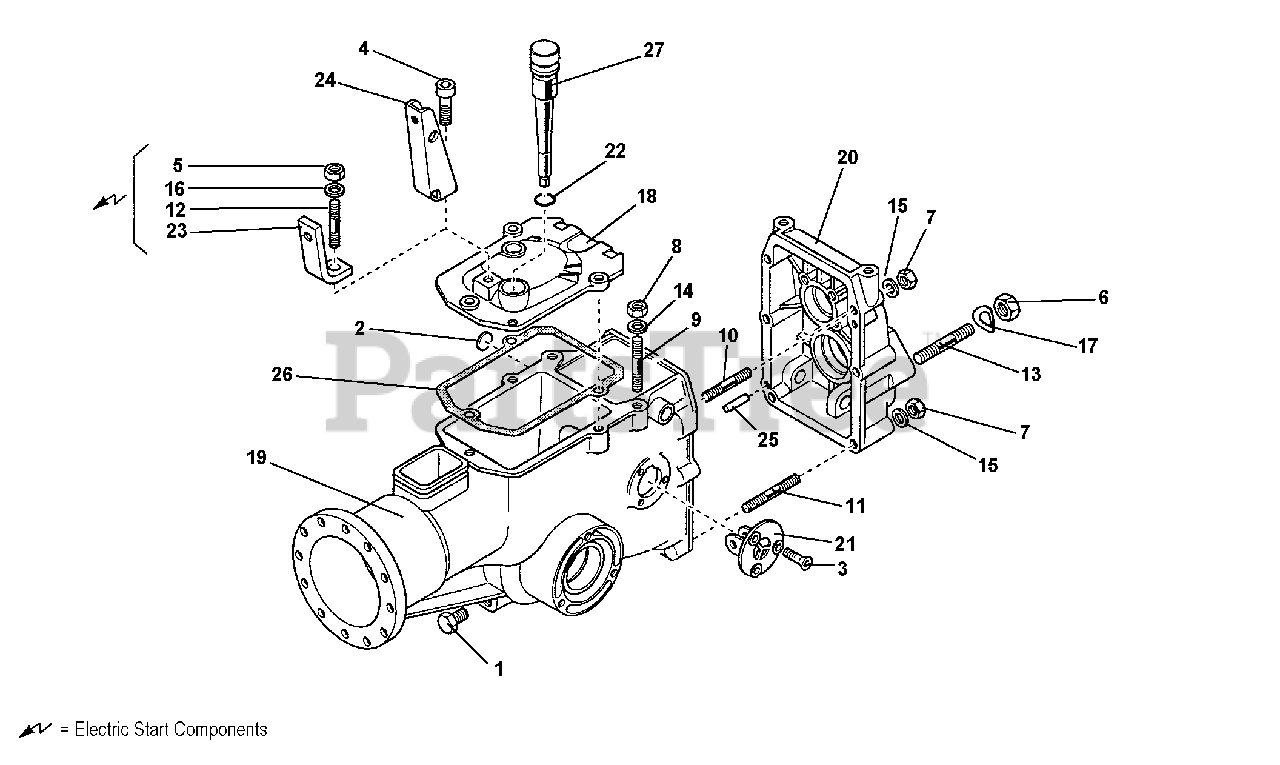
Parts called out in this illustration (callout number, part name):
3	SCREW, COUNTER SUNK, M6X16
4	SCREW M10X25
6	NUT, M12X1.25
7	NUT, SELF LOCKING M8
9	STUD M8X38X14X20
10	STUD M8X58X16X16
12	STUD M10X37
13	STUD M12X1.25X12X52
14	SUPER WASHER 8
15	WASHER, LOCK 8.4
16	WAHSER M10.4
17	WASHER, LOCK, M13
18	GEARBOX COVER
19	GEAR BOX CASE
21	REVERSER GEAR COVER, 710
23	CLUTCH BRACKET
24	CLUTCH BRACKET
25	PARALLEL PIN
26	GASKET, COVER
27	CAP WITH DIP STICK
